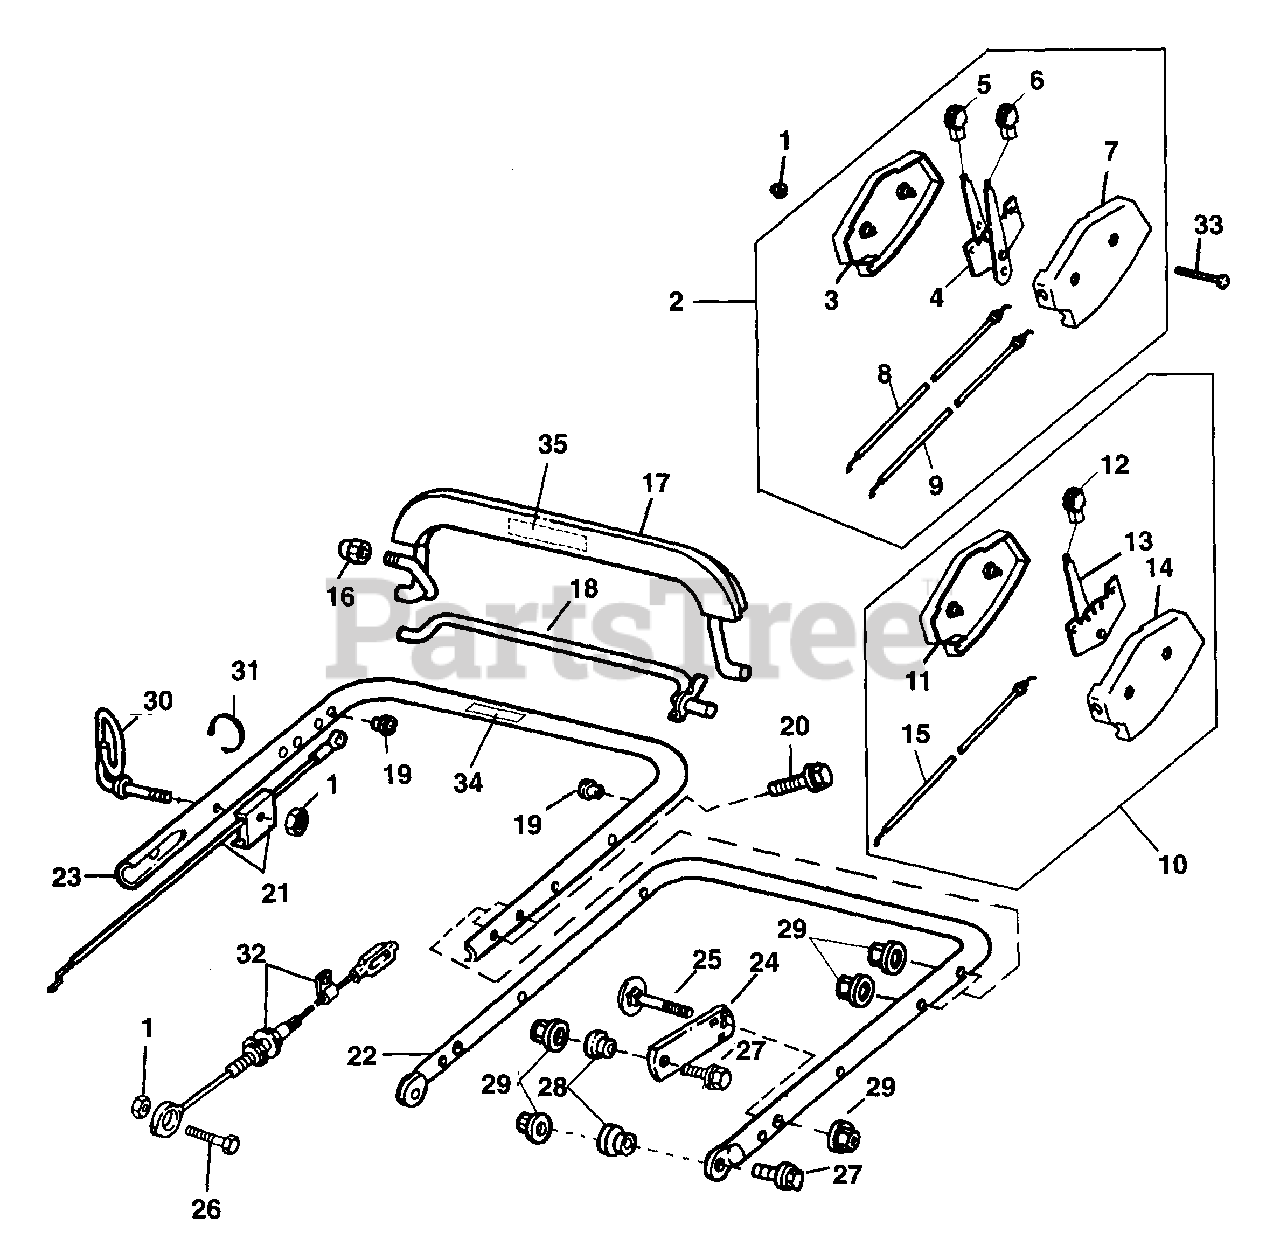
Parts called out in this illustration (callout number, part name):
1	NUT, Lock
2	THROTTLE CONTROL & SHIFT
3	CASE, Throttle RH
4	LEVER, Throttle
5	KNOB, Throttle
6	KNOB, Shift
7	CASE, Shift LH
8	CABLE, Throttle
9	CABLE, Shift
10	THROTTLE CONTROL
11	CASE, RH
12	KNOB, Throttle
13	LEVER, Throttle/Shift
14	CASE, Throttle LH
15	CABLE, Throttle
17	BAIL LEVER, OPC
18	BAIL LEVER, Traction
19	BUSHING, Anti-Rattle
20	BOLT, Upper Handle
21	CABLE, OPC
22	HANDLE, Lower
23	HANDLE, Upper
24	BRACKET, Handle Adjust
25	BOLT, Carriage
26	BOLT, Shoulder
27	BOLT, Lower Handle
28	SPACER, Lower Handle
29	NUT, Lock
30	BRACKET, Recoil Rope
31	TIE STRAP
32	CABLE, Traction
33	SCREW
34	LABEL, Caution
